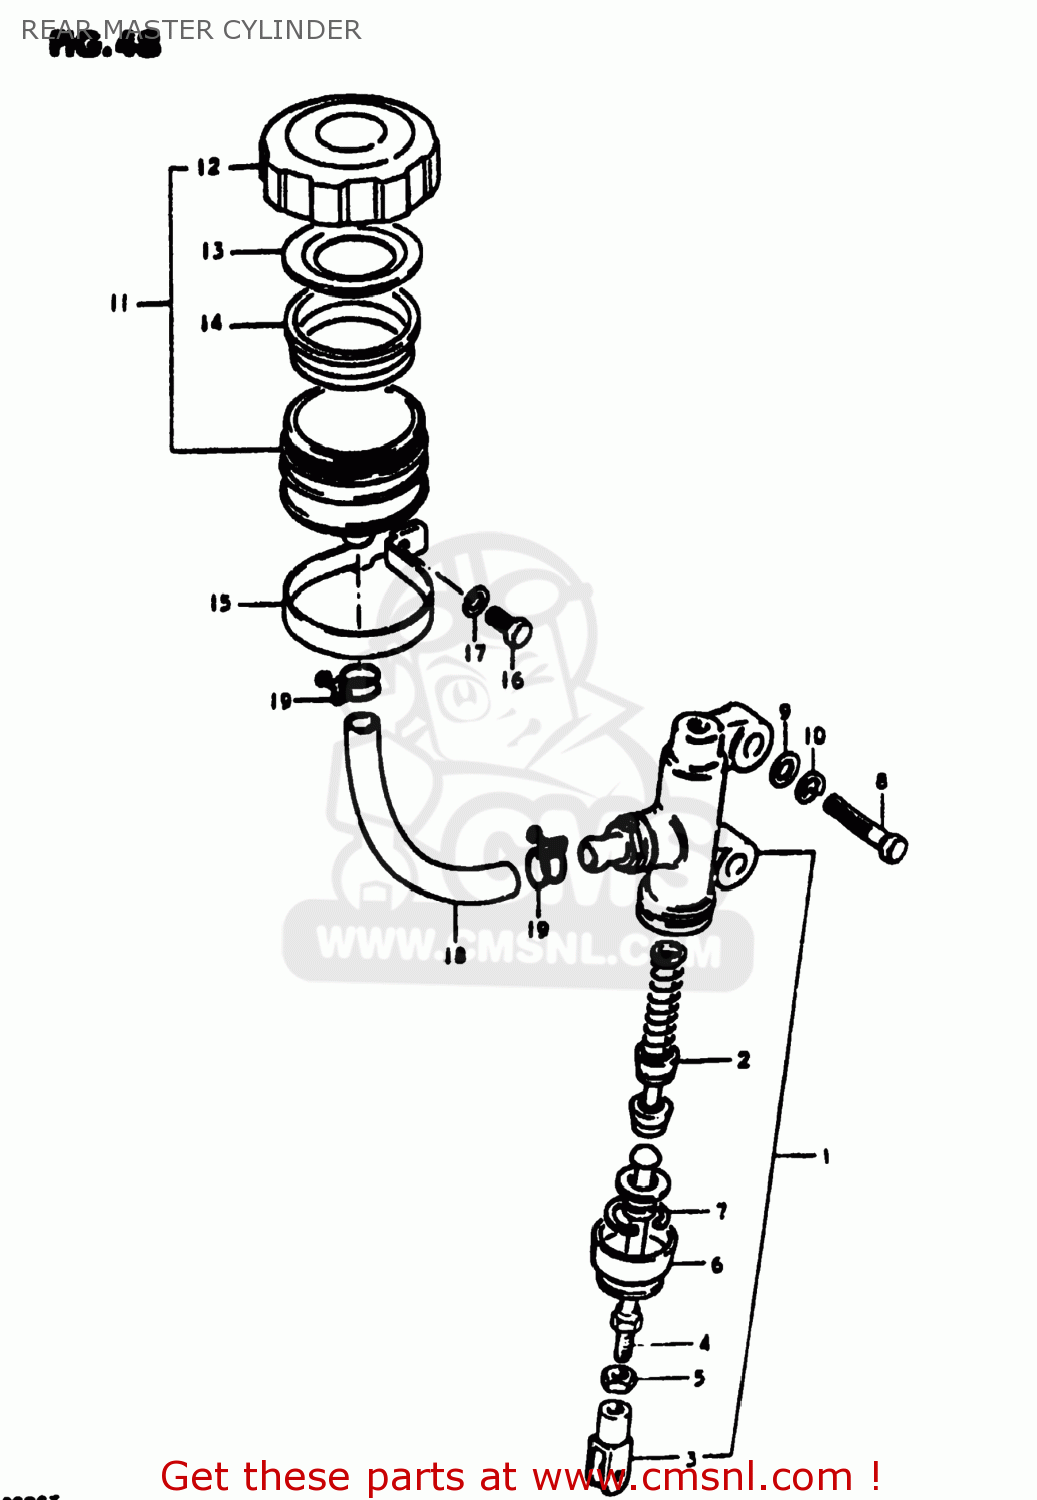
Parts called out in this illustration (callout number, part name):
1	CYLINDER ASSEMBLY,REAR MASTER
2	PISTON/CUP SET
3	YOKE
4	ROD,PUSH
5	NUT
6	BOOT
7	CIRCLIP
8	BOLT (8X30)
9	WASHER
10	LOCK WASHER
11	TANK ASSEMBLY,RESERVOIR
12	CAP
13	PLATE,DIAPHRAGM
14	DIAPHRAGM
15	CLAMP
16	BOLT, UPPER
17	LOCK WASHER
18	HOSE,RESERVOIR TANK
19	CLAMP
